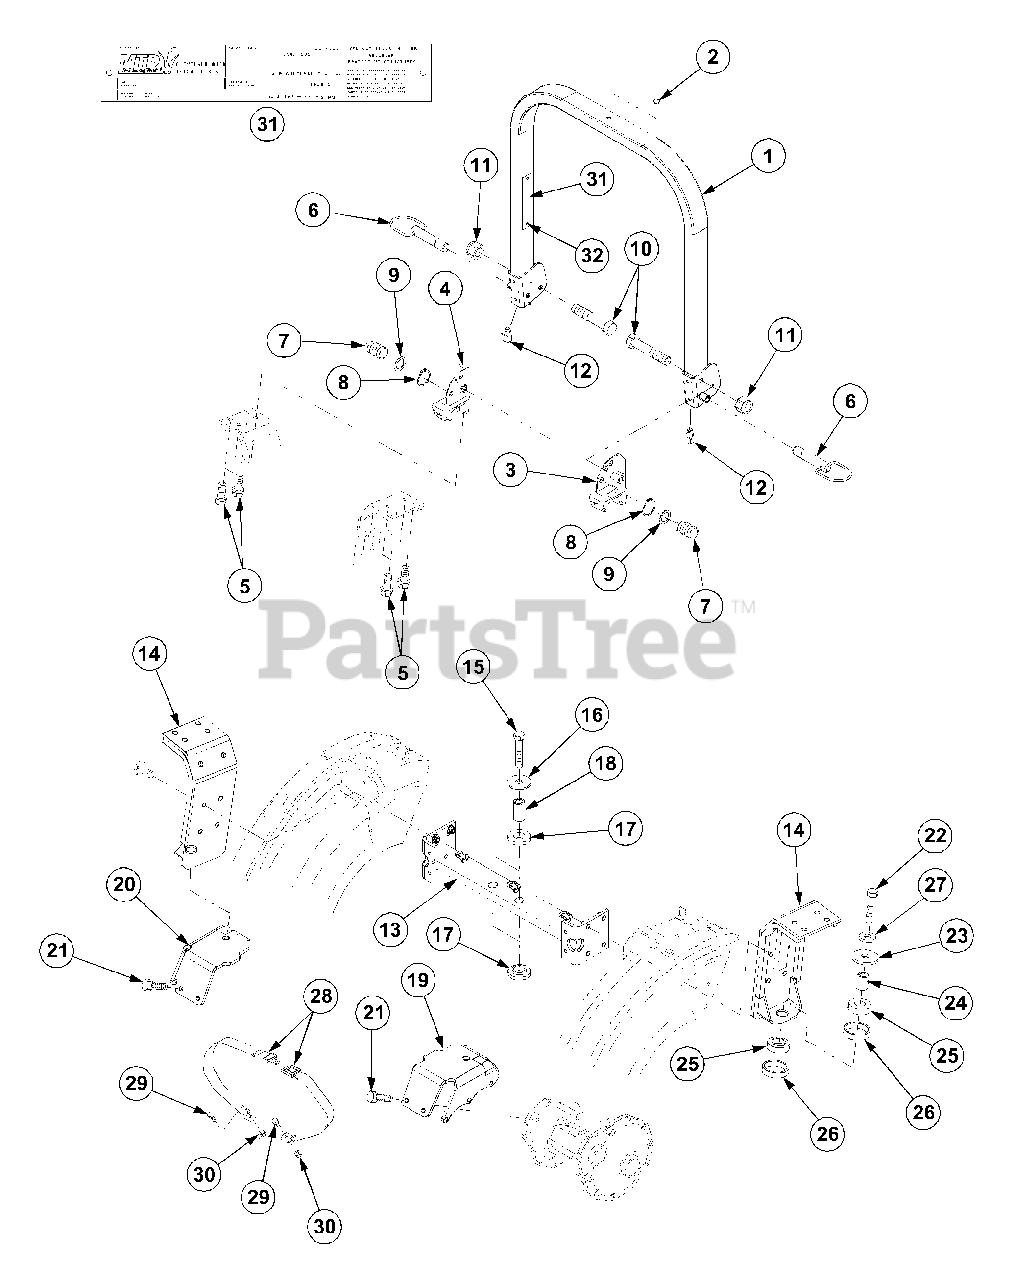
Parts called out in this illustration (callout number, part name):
5	Bolt,w/Washer
8	C-Ring
13	Support,Bracket
17	Rubber Cushion
19	Bracket LH,Rear
20	Bracket RH,Rear
21	Bolt,w/Washer
25	Rubber,Cushion
28	Seat Belt Assy
